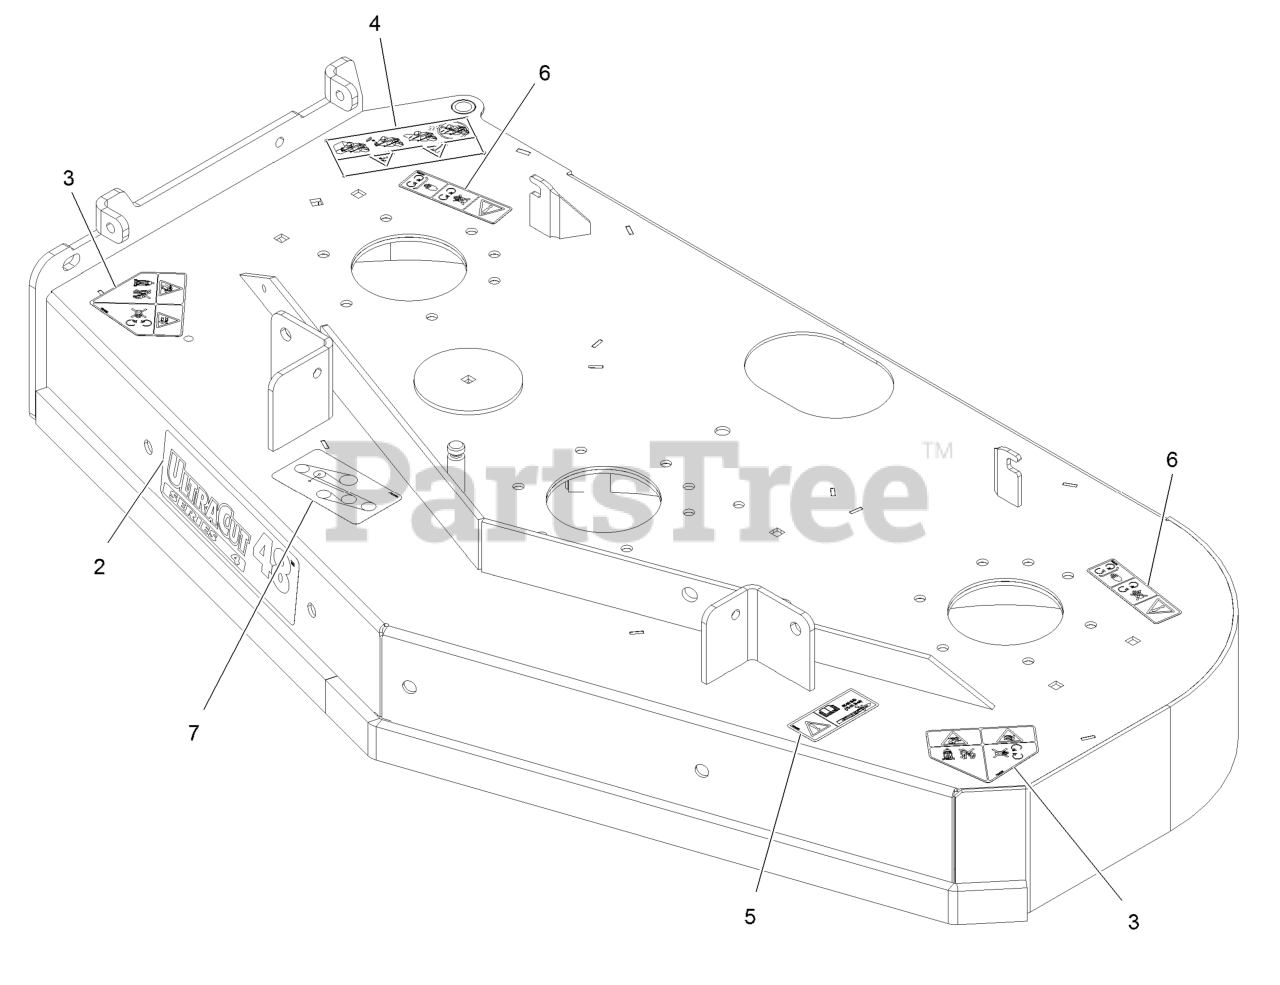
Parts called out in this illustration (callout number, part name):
2	DECAL,ULTRACUT 48 SERIES
3	DECAL-DANGER
4	DECAL-WARNING, BAGGER
5	DECAL-BOLT TORQUE
6	DECAL-COVER, MISSING
7	DECAL-BELT ROUTING
